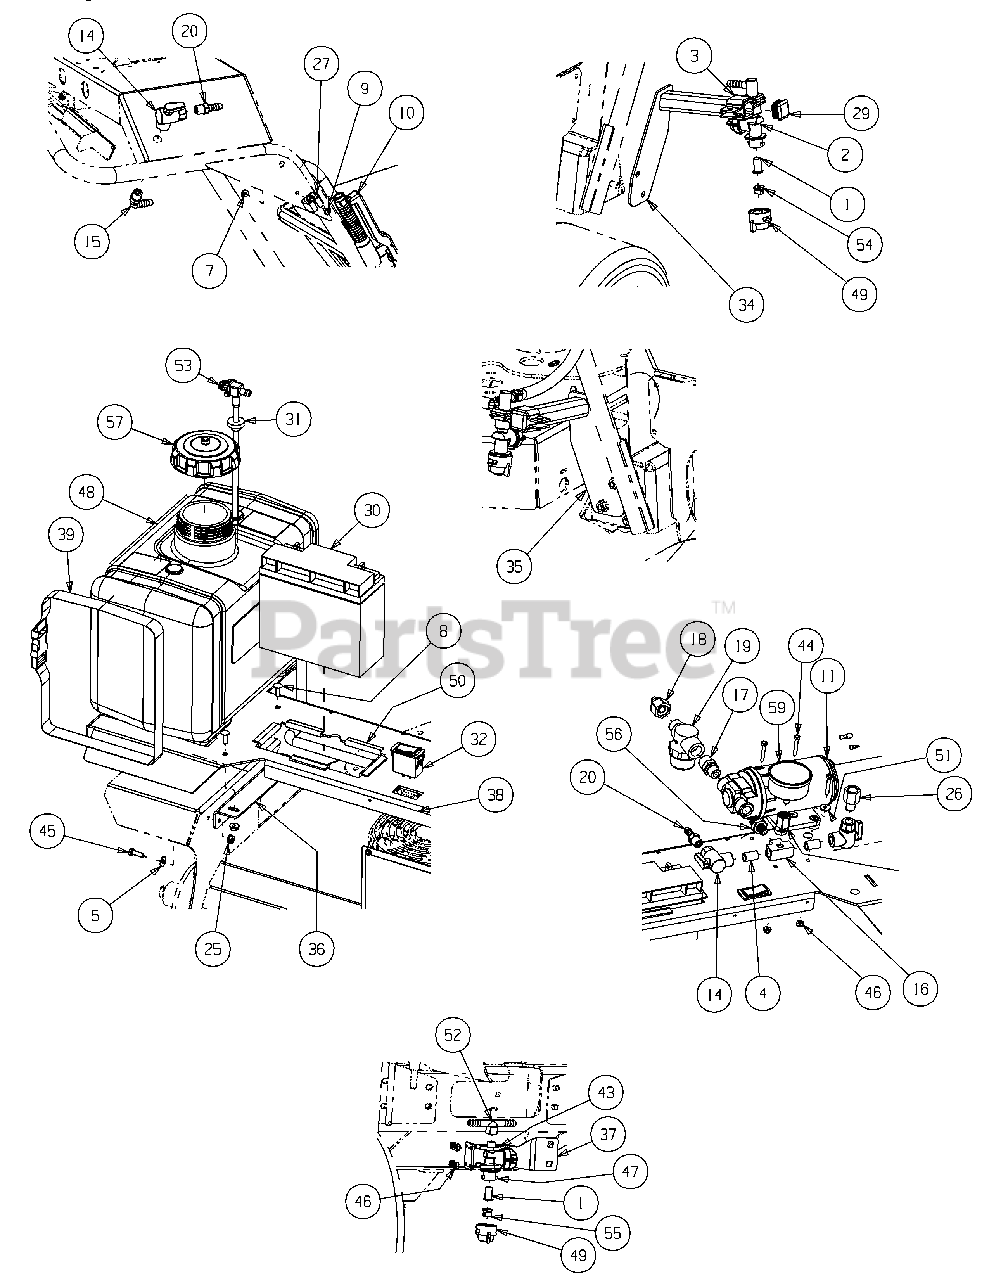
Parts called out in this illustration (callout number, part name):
1	Strainer Screen, 50 Mesh, SS
2	Single Dry Boom Nozzle Body
3	Nozzle Body Clamp, 1" SQ.
4	1/4" Brass Nipple
5	Washer, 1/4
7	Nut, #10-32, Nylon Insert
8	Carriage Bolt, 1/4-20 x .75
9	Phillips Head Screw, 10-32
10	Spray Wand
11	Pump, Flojet 25 GL
14	Valve, 1/4 90 Deg. Female
15	Fitting, 1/4 MPT x 3/8
16	Tee, 3/8 NPTF, Brass
17	Fitting, 8-145-00, Shurflo
18	Fitting, 8-060-01, Shurflo
19	Filter, 170-061-00, Shurflo
20	Fitting, 1/4 MET x 3/8 Barb, nylon
25	Nut, #10-24, Hex Flange Lock
26	Adaptor, 3/8 FNPT, 1/4 MNPT
29	Plastic Plug
30	Battery, 12CE18
31	Fuel Tank Grommet
34	Bracket Assembly, LH Nozzle
35	Bracket Assembly, RH Nozzle
38	Mounting Plate
39	Fuel Tank Mounting Strap
43	U-Bolt, #10-24
44	HHCS, #10-24 x 1.25
45	HHCS, 1/4-20 x .75
46	Nut, #10-24, Hex Flange Nylon
47	Nozzle Body, Center
48	Tank, 5 Gallon
49	Cap, Nozzle Body
50	Battery Edge Trim
51	Washer, .194 x .62 OD x .063
52	Tee Fitting, 1/4 NPTF x 3/8
53	Fitting, Sprayer Pickup
54	Fitting, Off Center Spray Tip
55	Fitting, Flat Spray Tip
56	Fitting, 3/8 NPTF x 1/4 NPTF
57	Fuel Cap
59	Pressure Gauge, 0-100 psi
